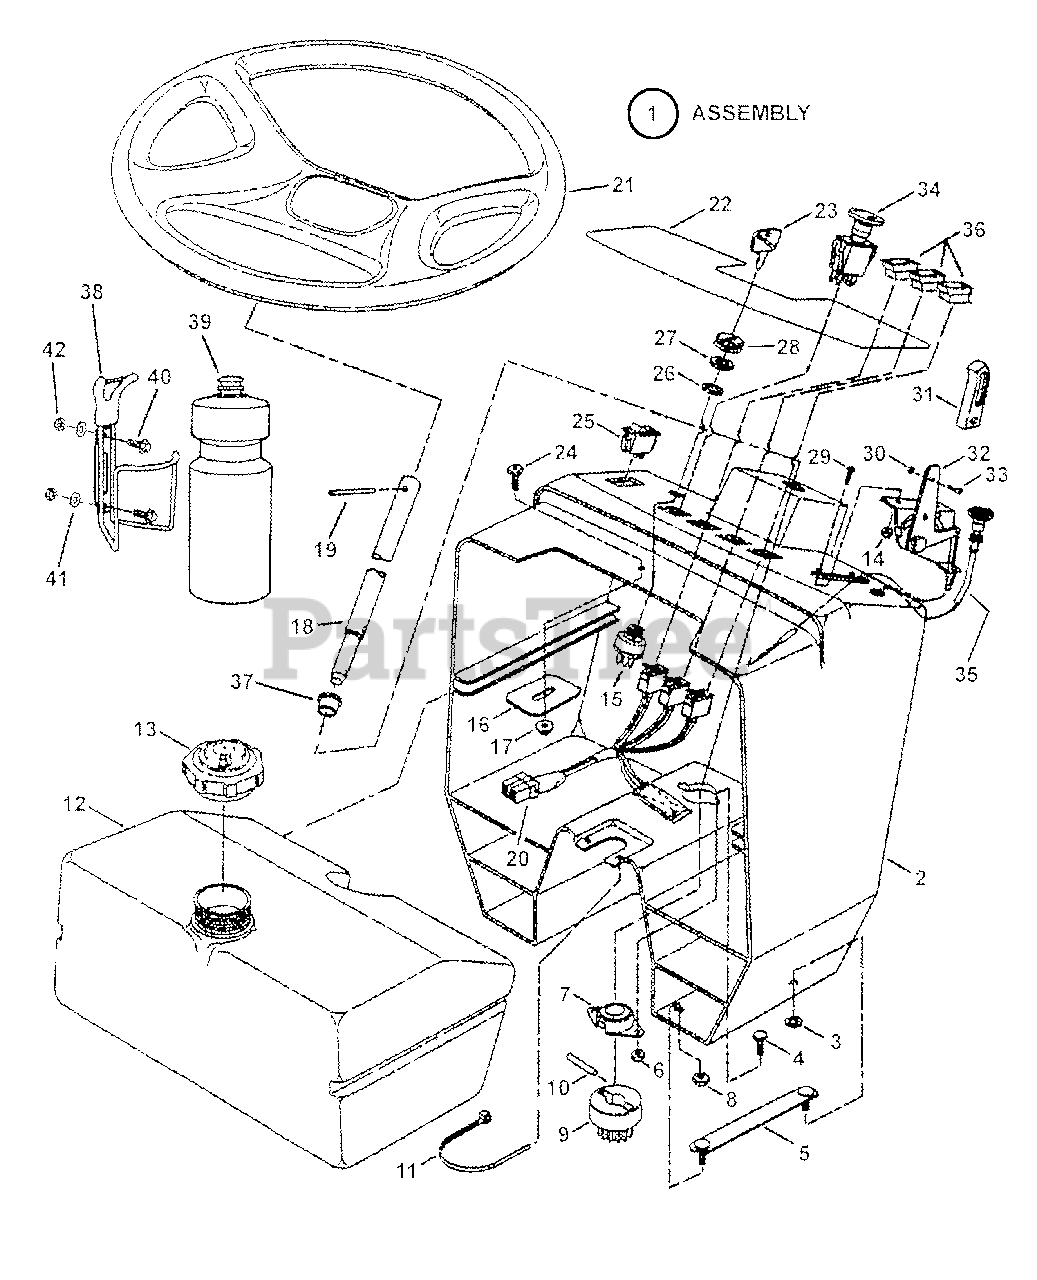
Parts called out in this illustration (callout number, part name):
1	ASSEMBLY, Console (Includes items 2 thru 7)
2	CONSOLE, OPPLT-Electric Clutch
3	RETAINER, 5/16" Bolt
4	SCREW, 1/4-20 x 3/4" Hex Head Cap, GR 5
5	ASSEMBLY, Strap-Clinch Stud
6	NUT, 1/4-20 Hex Nyloc
7	ASSEMBLY, BEARING, Flange .75 I.D. PM
8	NUT, 5/16-18 Hex Center Lock, GR 5 or B
9	GEAR, Pinion, Steering
10	PIN, Dowel, 1/4 x 1-1/4"
11	WIRE TIE, 1.29 long Black
12	ASSEMBLY, Fuel Tank/Cap 8-QT (Includes item 13)
13	CAP, Fuel Tank
14	NUT, #10-24 Hex Nyloc
15	SWITCH, Ignition-Afterfire Solenoid (Includes item 27)
16	NUT, 5/16-18 Hex Large Flange Center Lock
17	BRACKET, Hood Latch Catch
18	SHAFT, Steering
19	PIN, .26 x 2-1/4" Spiral
20	LIGHT CLUSTER, Indicator
21	STEERING WHEEL, Kelch Vector
22	DECAL, Console
23	KEY, Switch (With Cover)
24	SCREW, 5/16-18 x 5/8" Truss Head (Torx)
25	LIGHT SWITCH, Rocker SPST
26	SPACER, .65 x .88 x .10
27	NUT, 5/8-32 Hex
28	BEZEL
29	SCREW, #10-24 x 5/8" Flat Head Cross Countersunk Machine
30	NUT, #8-32 Hex, GR 2 or B
31	LEVER, Throttle Control
32	CONTROL, Throttle (conduit length: 44.60")
32	CONTROL, Throttle (conduit length: 26.25")
32	CONTROL, Throttle (conduit length: 48.0")
32	CONTROL, Throttle (conduit length: 47.60")
33	SCREW, #8-32 x 3/8" Cross-Recessed, Fillester Head, GR 2
34	SWITCH, PTO Electric Clutch
35	CABLE, Choke Control
35	CHOKE CABLE, 16HP Single Intek B&S
36	LENS, Indicator Light
37	BEARING, .750 I.D.
38	HOLDER, BOTTLE (wire)
39	BOTTLE, Water
40	SCREW, #10-24 x 5/8" Hex Washer Self-Tap
41	WASHER, .219 x .500 x .049 Flat
42	NUT, #10-24 Hex Nyloc
